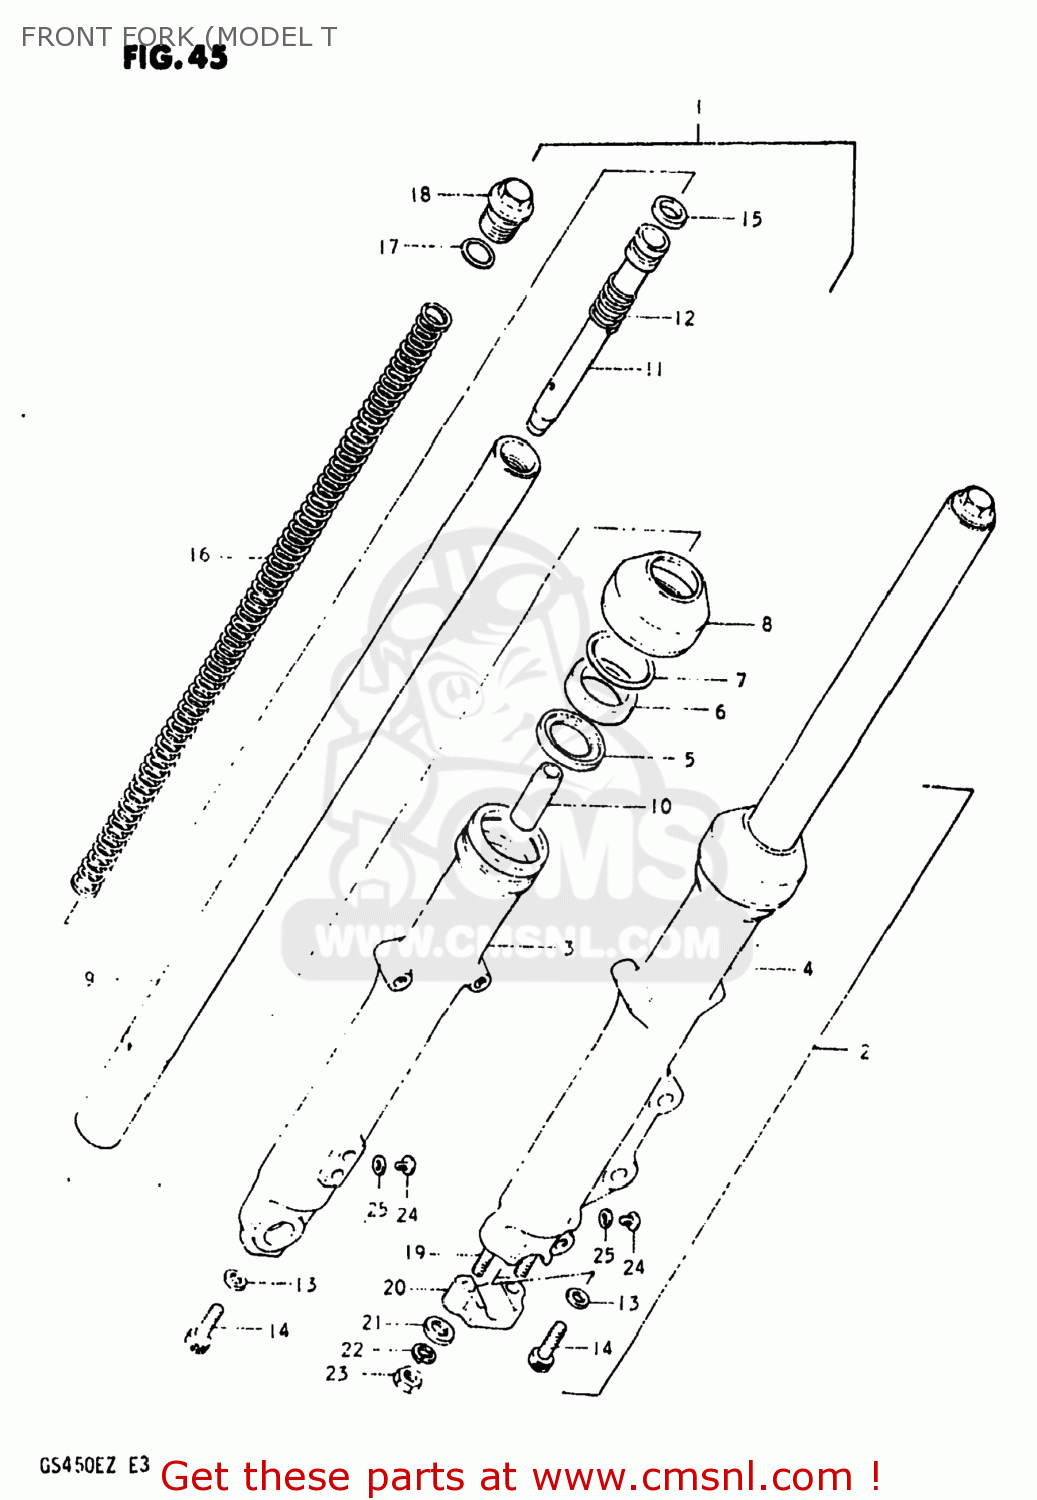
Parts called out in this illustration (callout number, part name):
1	DAMPER ASSEMBLY,RIGHT
2	DAMPER ASSEMBLY,LEFT
3	TUBE,FORK,OUTER,RIGHT
4	TUBE,FORK,LEFT,OUTER
5	SPACER,OIL SEAL
6	OIL SEAL,FRONT FORK
7	CIRCLIP,FORK OIL SEAL
8	DUST SEAL
9	TUBE,INNER
10	PIECE,OIL LOCK
11	CYLINDER,FRONT FORK
12	SPRING,REBOUND
13	GASKET (NAS)
14	BOLT(8X27)
15	RING,PISTON
16	SPRING
17	O RING
18	BOLT
19	STUD 8X25
20	HOLDER,AXLE
21	WASHER
22	LOCK WASHER
23	NUT (8MM)
24	SCREW 4X6
25	GASKET (NAS)
